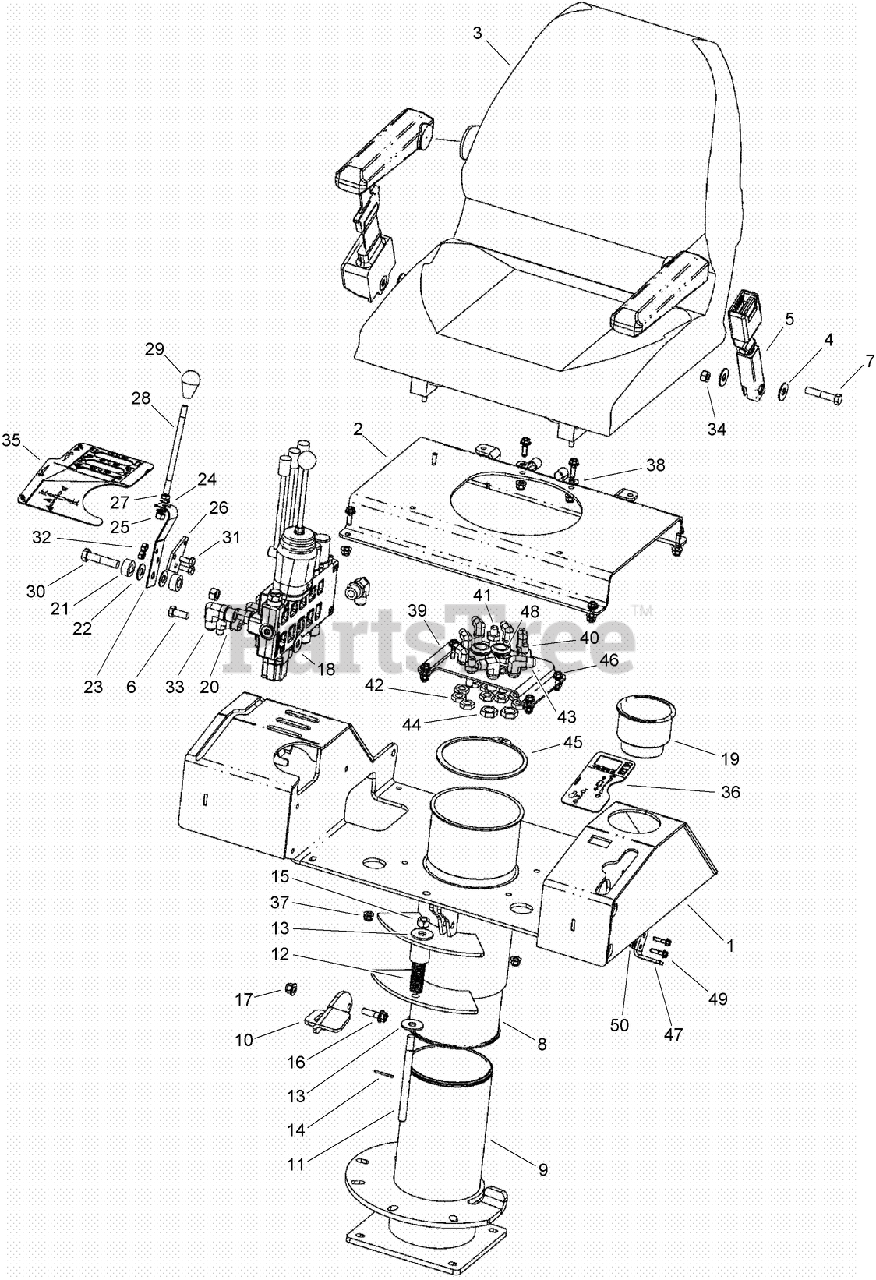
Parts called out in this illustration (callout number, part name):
1	WELDMENT-Seat Mount
2	WELDMENT-Seat Mount
3	SEAT ASM
4	WASHER-FLAT
5	SEAT BELT ASM
6	SCREW-HH
7	SCREW-HH
8	BEARING-SEAT PIVOT BUSHING
9	MOUNT-SEAT
10	PLATE-Seat Latch
11	ROD-SWING, SEAT
12	SPRING-PIVOT LOCK, SEAT
13	WASHER-FLAT
14	PIN-COTTER
15	NUT-Hex 0.500-13 GR5 ZND
16	SCREW-HHF
17	NUT-FLANGE, NYLOCK
18	HYD CONTROL VALVE ASM
19	CUP-HOLDER
20	ELBOW-90 Adj 37FL, 3/8 x 1/2 Tube
21	SPACER-GEARBOX
22	WASHER-Friction
23	LEVER-Speed Control
24	WASHER-3/8 HT
25	NUT-Hex 0.375-16 GR5 ZND
26	PLATE-Cable Mtg
27	NUT-Hex Jam 0.375-16 GR5 ZNd
28	ROD-Linkage
29	KNOB-Control
30	BOLT-Hex Hd 0.500 x 2.25 GR8 ZND
31	BOLT-Hex Hd 0.312 x 0.75 GR5 ZND
32	NUT-Hex 0.312-18 GR5 ZND
33	ELBOW-90 Adj 37FL 5/8 Tube
34	NUT-Hex 0.438-20 UNF GR5 ZND
35	DECAL-Controls, RH
36	DECAL-Controls, LH
37	NUT-TORQUE, PREVAILING
39	PLATE-Seat Bulkhead
41	UNION-BULKHEAD
42	NUT-LOCK, BULKHEAD
44	NUT-LOCK
45	RING-RETAINING
46	SCREW-HH
47	PLATE-Mount
48	GROMMET-Rubber
49	SCREW, METRIC FLANGE w/BODY-M6 x 25
50	NUT, METRIC FLANGE PREVAILING - M6 Zinc
